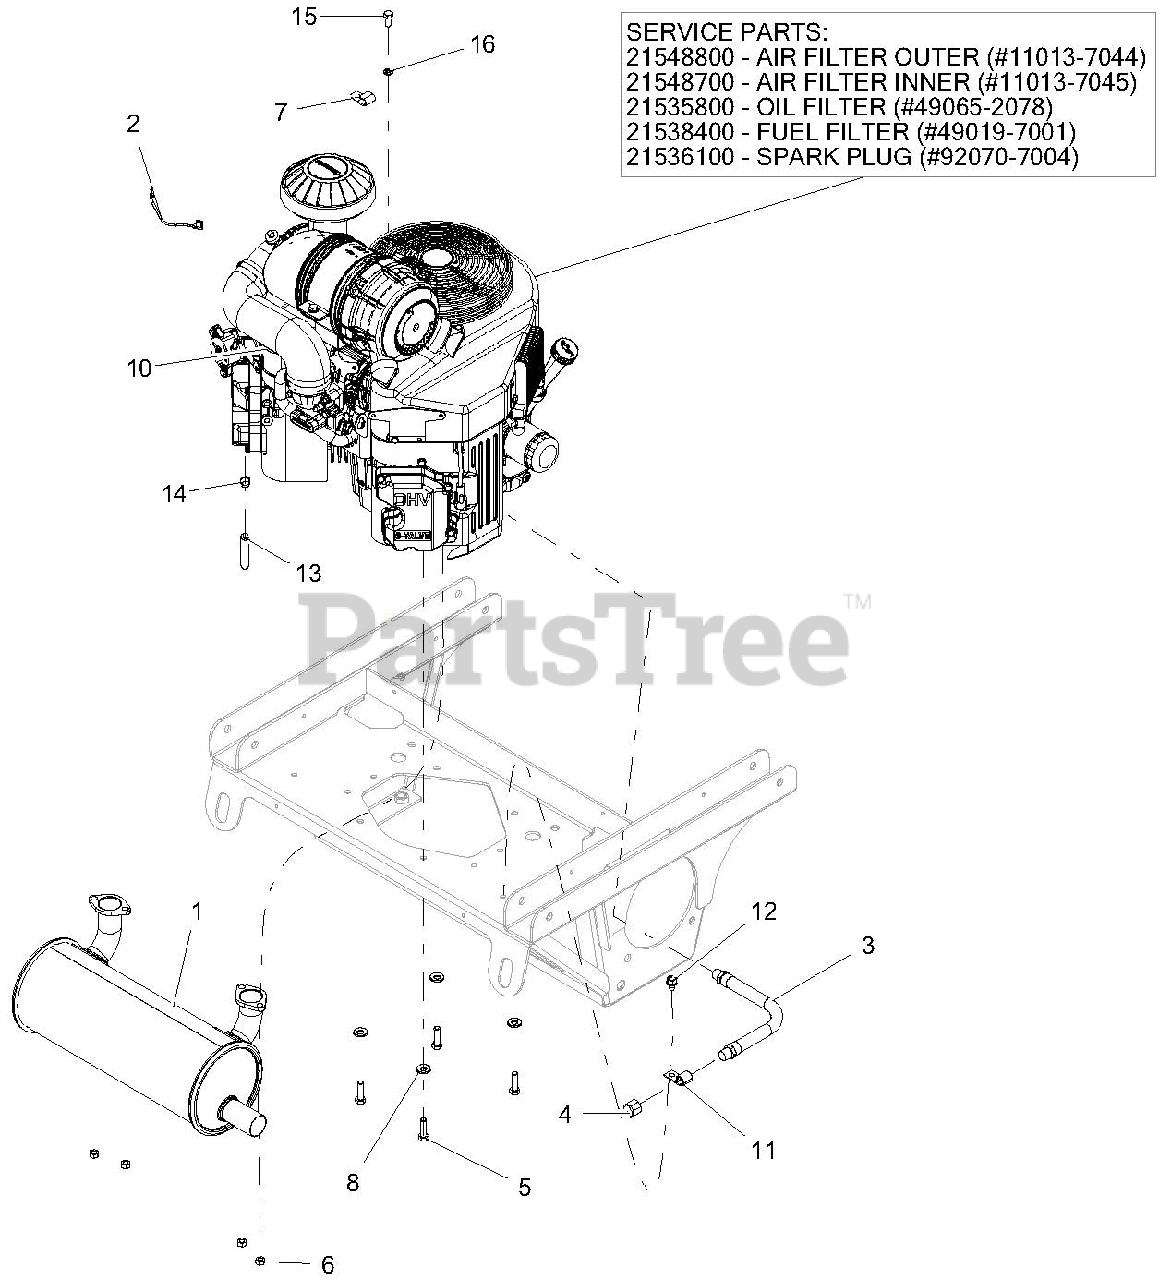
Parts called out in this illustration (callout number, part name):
1	MUFFLER - 34HP KAWASAKI VERT
2	LEAD - STARTER SOLENOID
3	HOSE, HYD .38-11-0K M6N0-M6N0
4	PIPE, CAP 3/8 NPT FEMALE
5	BLT-HEX .38-16X1.25 GR5 YWZC NYTORQ
6	NUT-LK-TOP M8-1.25 YWZC
7	CLAMP, J
8	WSHR, 3/8" SPRING DISC
10	ENGINE, KAWASAKI FX1000
10	AIR FILTER OUTER (#11013-7044)
10	AIR FILTER INNER (#11013-7045)
10	OIL FILTER (#49065-2078)
10	FUEL FILTER (#49019-7001)
10	SPARK PLUG (#92070-7004)
12	SCR-TAP .38-16X.50 HWH TR YWZ
13	.25 LOW-PERM GAS HOSE 28.00" LG
14	CLAMP, FUEL LINE
15	@BLT-HEX M8-1.25X20 YWZC
16	WSHR-LK .31X.078 REG YWZC
